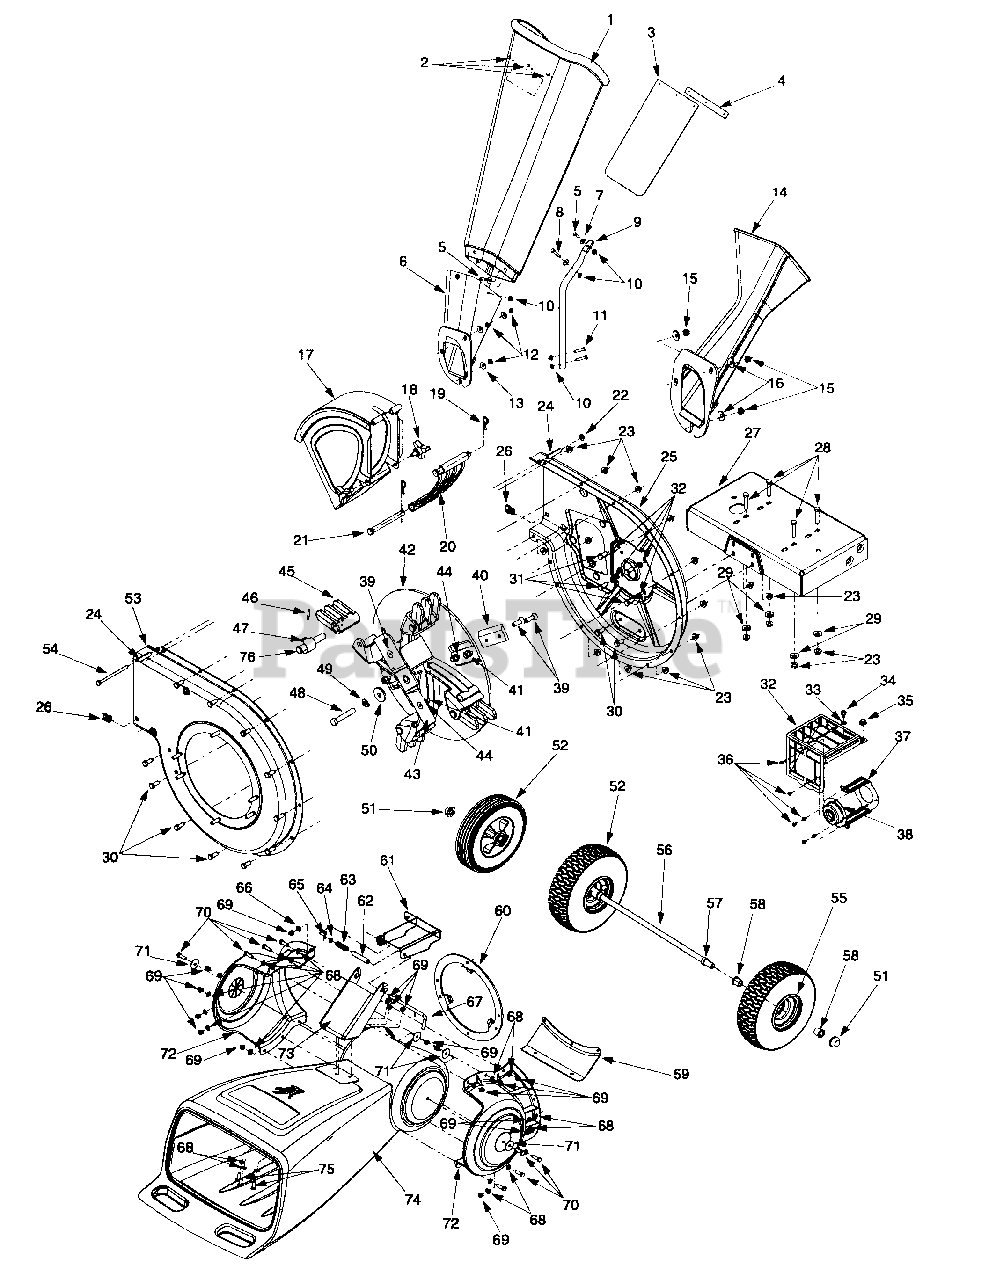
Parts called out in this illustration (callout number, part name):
1	Chipper Chute
2	Pop Rivet
3	Chute Flap
4	Flat Strip
5	Hex Cap Screw 1/4-20 x .620
8	Hex Cap Screw 1/4-20 x 1.25
10	Hex Flange Nut 1/4-20
11	Hex Cap Screw 1/4-20 x 1.25
12	Hex Nut 5/16-18
13	Bell Washer .340 ID x .872 OD
15	Hex Nut 5/16-18
16	Bell Washer .340 ID x .872 OD
18	Knob 5/16-18
19	Cotter Pin
21	Clevis Pin
22	Hex Lock Nut 1/4-20
23	Flange Hex Lock Nut 5/16-18
24	Spacer
26	U Nut 5/16-18
28	Hex Cap Screw 5/16-18 x 1.5
29	Bell Washer 5/16 x 1.0
30	Hex Cap Screw 5/16-18 x .75
31	Hex Cap Screw 5/16-24 x .75
32	Lock Washer 5/16
33	Lock Washer 1/4
34	Hex Washer Screw 1/4-20 x .5
35	Hex Lock Nut 5/16-18
36	Hex Washer Screw
37	Muffler Bracket Guard
38	Deflector
39	Flat Screw 5/16-24 x 1.0
40	Chipper Blade
41	Hex Lock Nut 5/16-24
42	Impeller Asm
43	Shredder Blade
44	Lock Washer 5/16
45	Flail Blade
46	Spiral Pin
47	Spring Pin
48	Hex Cap Screw 3/8-24 x 2.25
49	Lock Washer 3/8
50	Flat Washer 3/8 x 1.25
51	Push Cap
52	Wheel Assy Comp 10.0 x 2.5
54	Hex Cap Screw 1/4-20 x 3.75
57	Spacer
58	Flange Bearing
62	Spacer
63	Compression Spring
64	Flat Washer 3/8 x .620 x .033
65	Cotter Pin
66	Flat Washer
67	Hex Lock Nut 5/16-18
68	Flat Washer .330 ID x .630 OD
69	Hex Lock Nut 5/16-18
70	Hex Cap Screw 5/16-18 x 1.0
71	Flat Washer .320 ID x 1.25 OD
72	Collar-Hopper
74	Hopper
75	Hex Cap Screw 5/16-18 x .75
76	Clevis Pin
